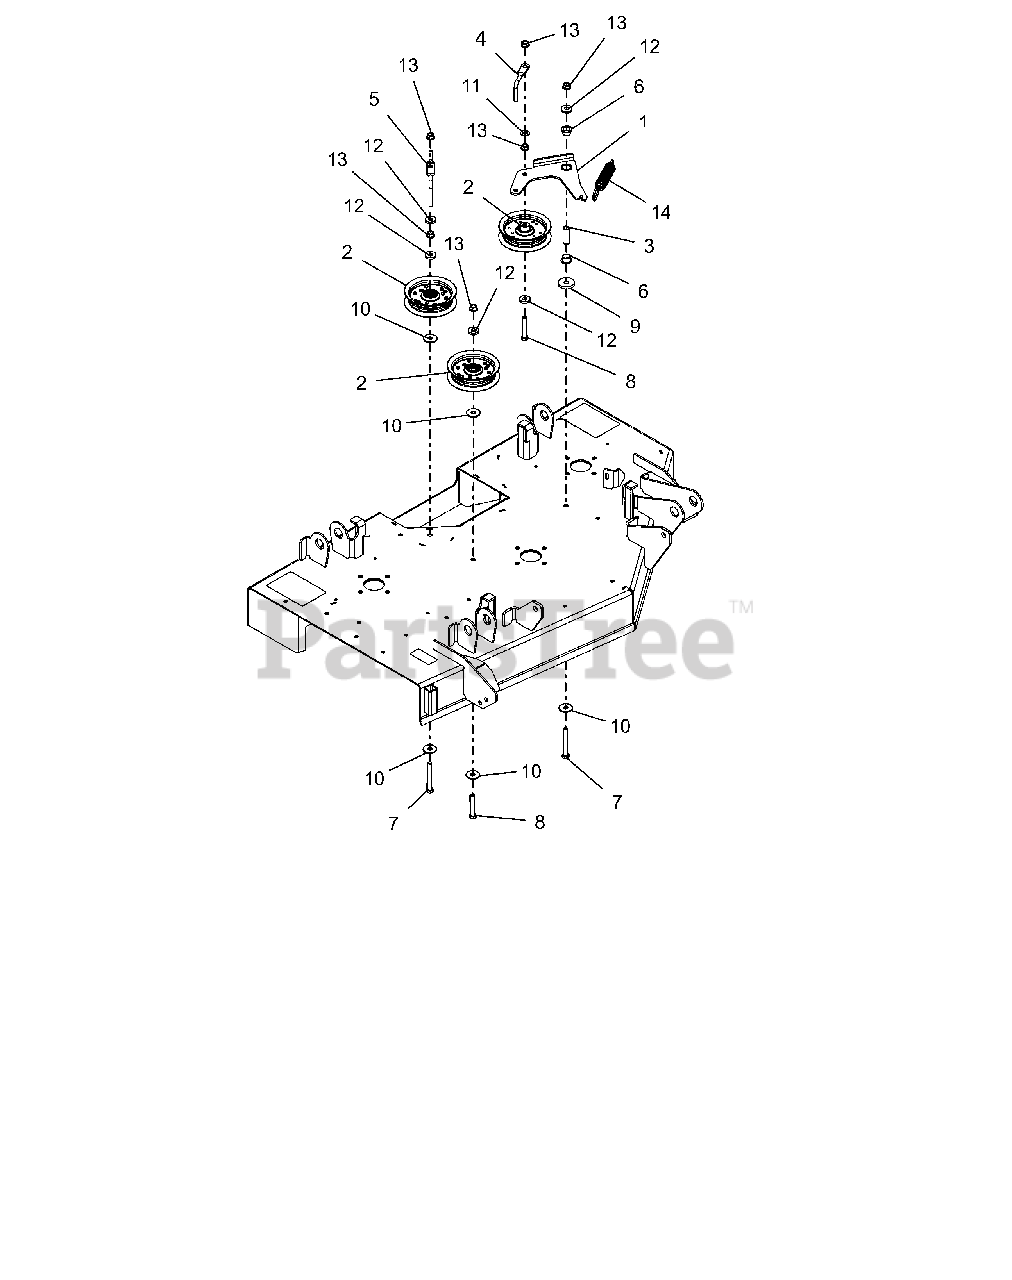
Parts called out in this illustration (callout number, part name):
1	WLDMT, IDLER ARM-42"
2	ASM, IDLER 4"
3	SPACER, .375IDX.625ODX1.66 PM
4	WIREFORM, BELT FINGER
5	WIREFORM, BELT FINGER
6	BSHG-FLG, .625X.750X.500X1.00
7	BLT-HEX .38-16X3.00 GR5 FTH YZ
8	@BLT-HEX .38-16X2.25 GR5 YWZC
9	WSHR,FLT STL.406X1.50X.245YWZC
10	WSHR-FL-STL .406X1.25X.10 ZC
11	@WSHR-FL-STL.406X.812X.065 YWZ
12	WSHR-FL-STL .406X1.00X.188 YWZ
13	@NUT-LK-TOP-FLG .38-16 YWZC
14	SG-TENS .135X.98X6.0 WLD 62
